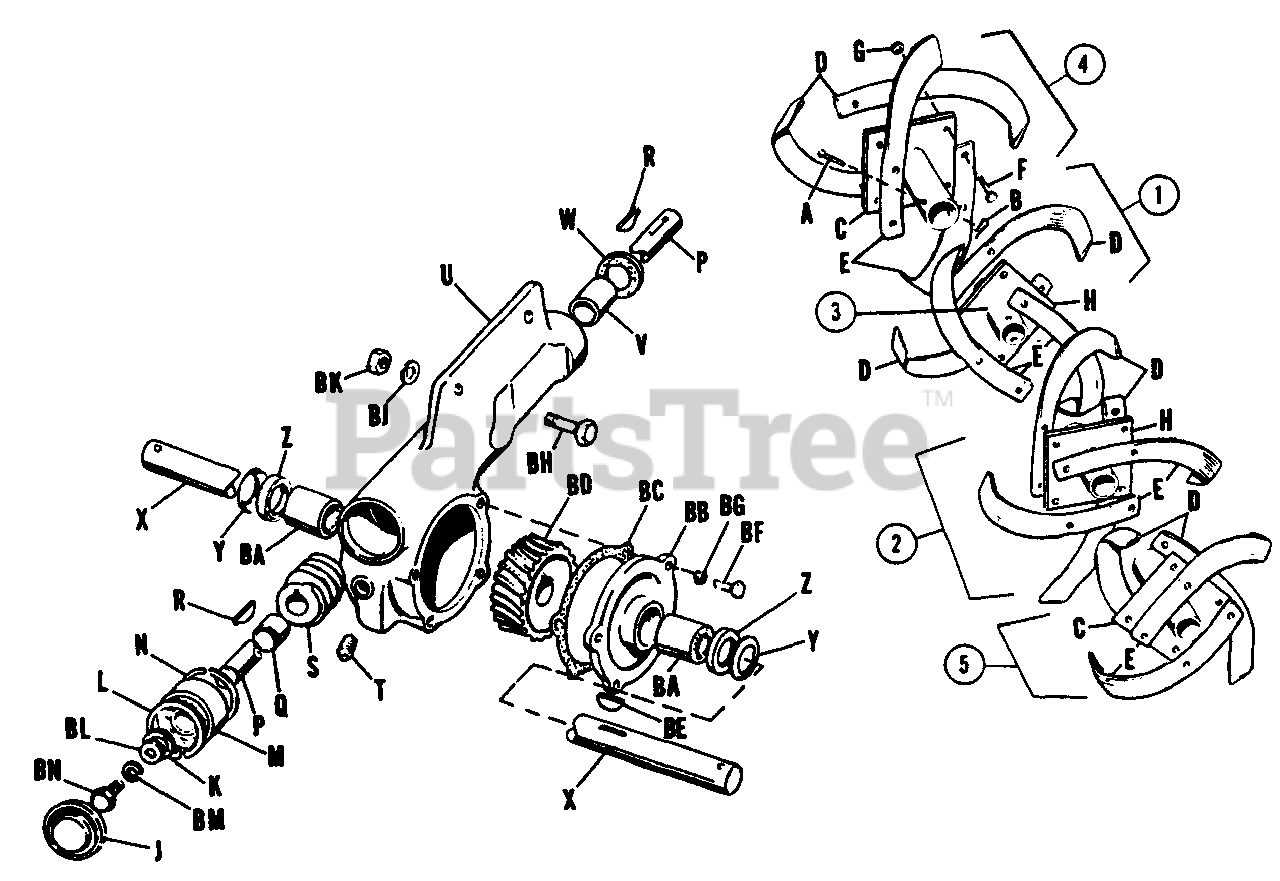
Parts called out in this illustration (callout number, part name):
A	Pin
B	Clip, Spring
C	Tine Plate Assembly, Outer
D	Tine Blade, L.H.
E	Tine Blade, R.H.
F	Capscrew, Hex Hd., 7/16-20 x 1 1/4
G	Hex Nut, Full Lock, 7/16-20
H	Tine Plate Assembly, Inner
L	Retaining Ring
M	Ball Bearing
N	Snap Ring
P	Worm Shaft
R	Key, Hi-Pro #706
T	Pipe Plug, 3/8" Std.
U	Worm Drive Housing
X	Worm Gear Shaft
BA	Bearing, Needle
BE	Key, Woodruff, 1/4" x 3/4"
BF	Capscrew, Hex Hd., 1/4-20 x 5/8"
BG	Lock Washer, 1/4"
BH	Capscrew, Hex Hd., 3/8-16 x 1 1/4"
BJ	Lock Washer, 3/8"
BK	Hex Nut, Full, 3/8"-16
BL	Washer, Plain, 5/16"
BM	Lock Washer, 3/8"
BN	Capscrew, Hex Hd., 3/8-16 x 3/4"
